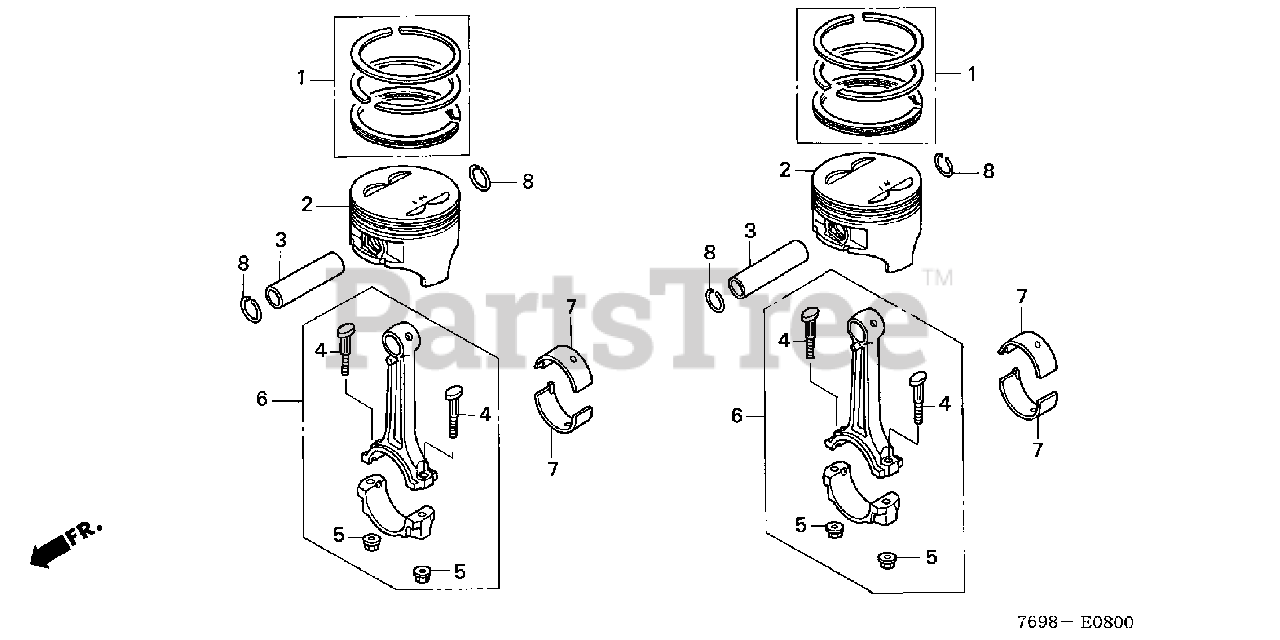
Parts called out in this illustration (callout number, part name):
1	RING SET, PISTON (STD)
1	RING SET, PISTON (OS 0.25)
1	RING SET, PISTON (OS 0.50)
2	PISTON (STD)
2	PISTON (OS 0.25)
2	PISTON (OS 0.50)
3	PIN, PISTON
4	BOLT, CONNECTING ROD (TOKAI TRW)
5	NUT, CONNECTING ROD
6	ROD ASSY., CONNECTING
7	BEARING A, CONNECTING ROD (BLUE)
7	BEARING B, CONNECTING ROD (BLACK)
7	BEARING C, CONNECTING ROD (BROWN)
7	BEARING D, CONNECTING ROD (GREEN)
7	BEARING E, CONNECTING ROD (YELLOW)
7	BEARING F, CONNECTING ROD (PINK)
7	BEARING G, CONNECTING ROD (RED)
8	CLIP, PISTON PIN (19MM)
